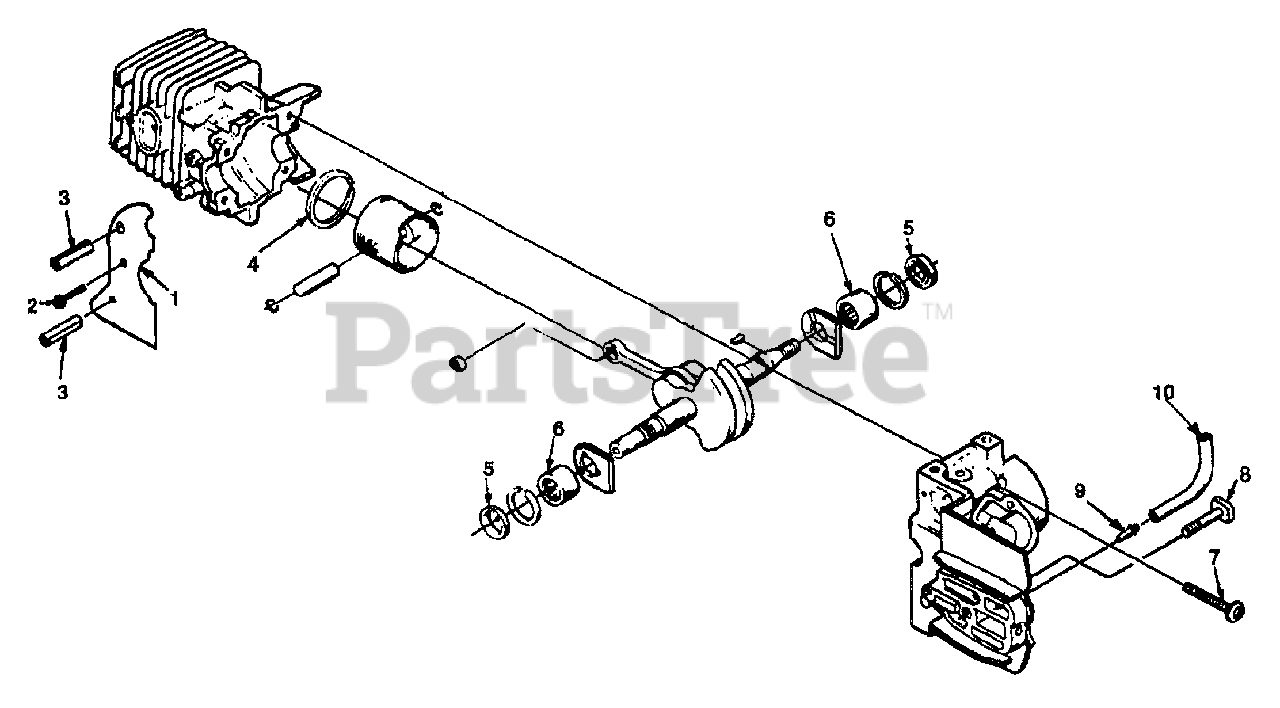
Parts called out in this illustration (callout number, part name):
1	SAW DUST SHIELD
2	SCREW- Tapping (#6-32 x 5/16")
3	PIN- Roll (5/32 x 1 1/8")
4	RING- Piston
5	SEAL- Shaft
6	BEARING- Needle
7	SCREW- Torx Pan Hd. (10-24 x 1 1/8")
8	BOLT-Guide Bar
9	FITTING- Tube
10	TUBING- Rubber (Oil Line) (4 1/4")
